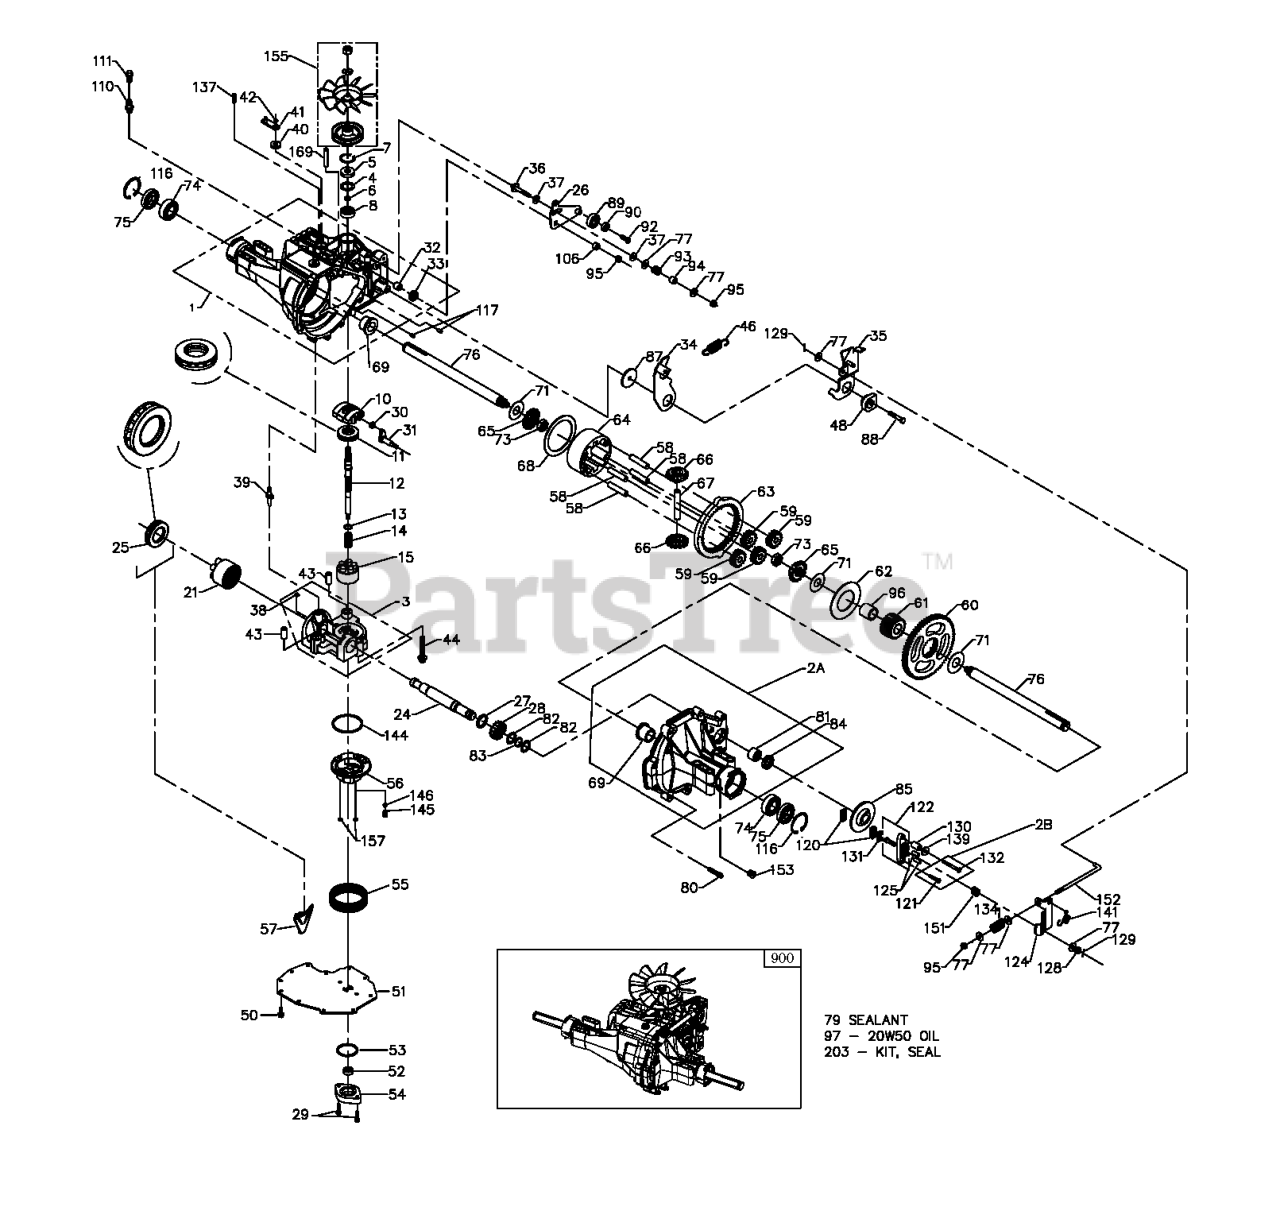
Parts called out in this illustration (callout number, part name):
5	SEAL.LIP.H-G.(9008000-0128)
6	RING RETAINING 2003016
7	RING.RETAINING.(2003052)
8	BALL BEARING
12	INPUT SHAFT 50795
14	SPRING 2003014
15	KIT CYLINDER #70331
26	CONTROL.ARM.50857
30	SLOT GUIDE
37	DAMPENER PUCK
41	BYPASS ARM
42	RETAINING RING 44870
53	O-RING.HYDRO GEAR.9004101-1340
77	WASHER .34X.88X.06.44130
80	TORX.SCREW. 50868
93	SPRING HELICAL COMP 50277
94	SPACER.HYDRO GEAR 50278
120	BRAKE PUCK (44132)
121	BOLT RIB NECK 50874
131	PUCK PLATE 44134
